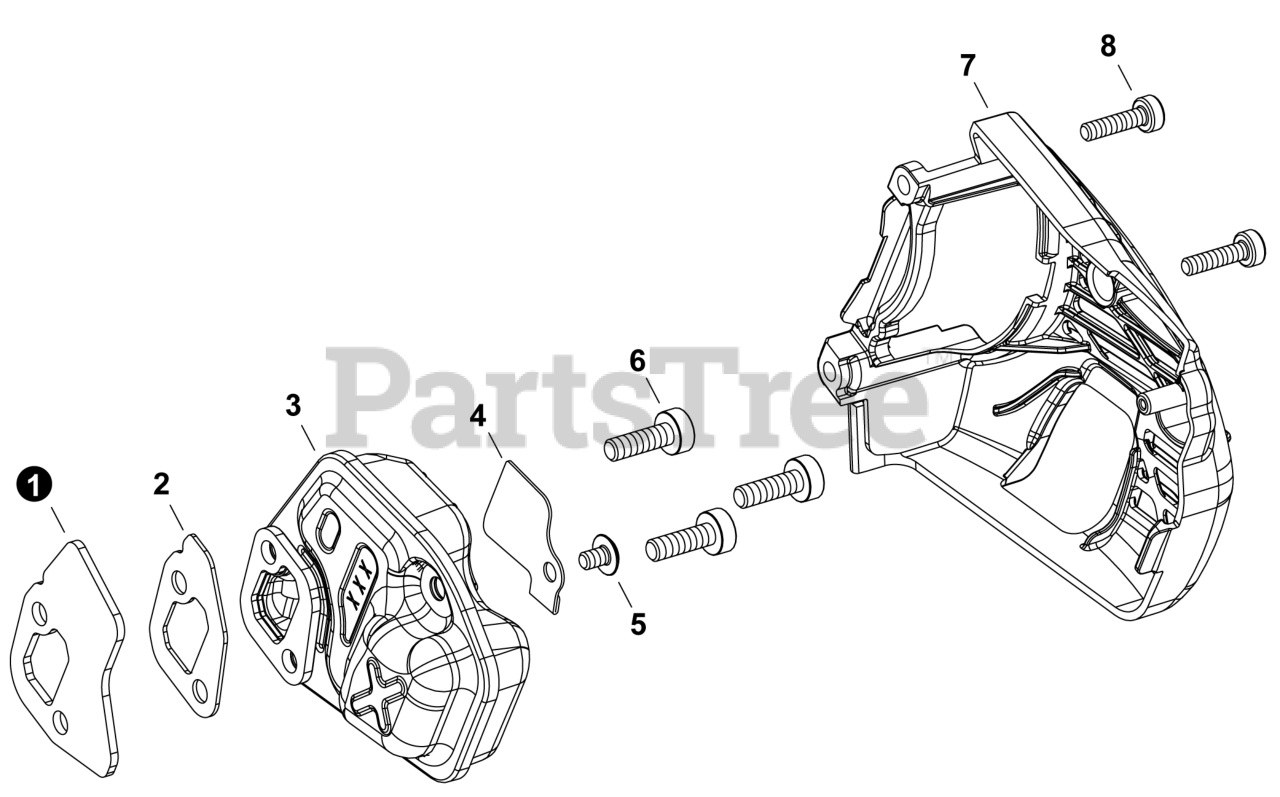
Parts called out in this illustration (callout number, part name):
1	HEAT SHIELD, EXHAUST
2	GASKET, EXHAUST
3	MUFFLER ASSY
4	SCREEN, SPARK ARRESTER
5	SCREW 4x6
6	BOLT, TORX 5x16
7	COVER, MUFFLER
8	BOLT, TORX 4x16
